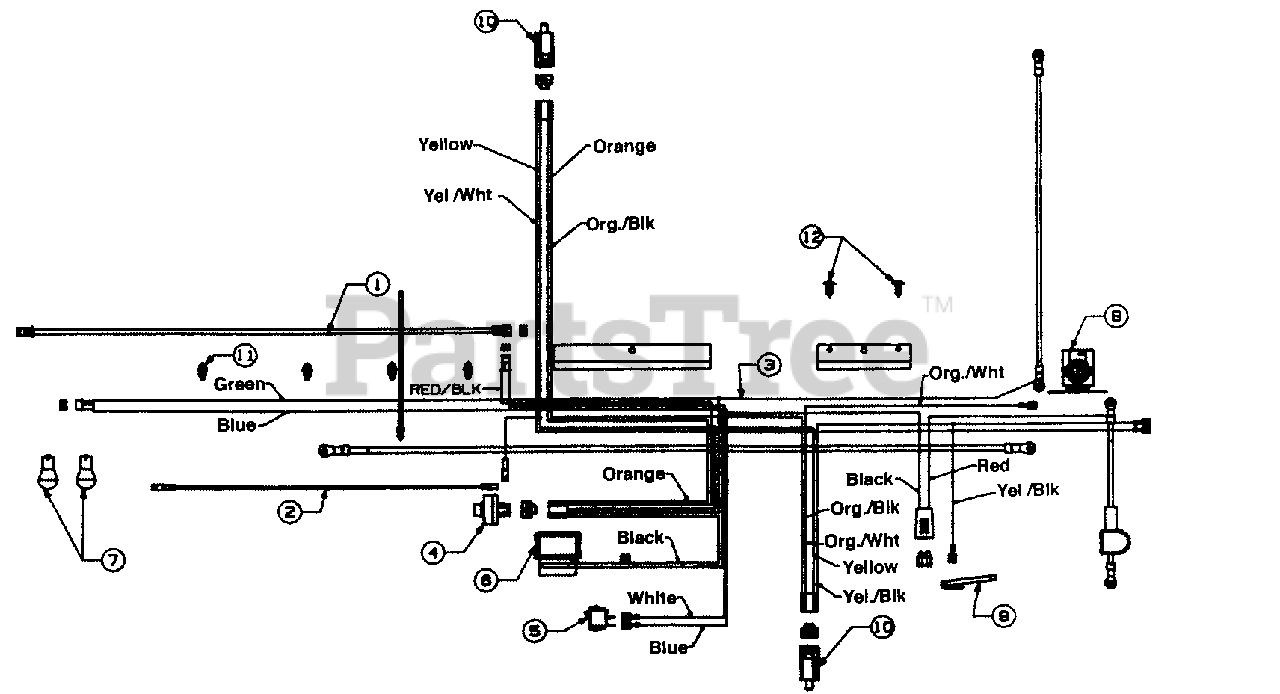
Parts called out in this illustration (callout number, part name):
1	Harness Adapter (Alt.)
2	Harness Adapter
3	Wire Harness w/Light Switch and Amp
4	Ignition Switch
5	Light Switch
6	Ammeter
7	Bulb
8	Solenoid
9	Safety Switch (Reverse)
10	Safety Switch
11	Wire Retainer Clip
12	Ratchet
